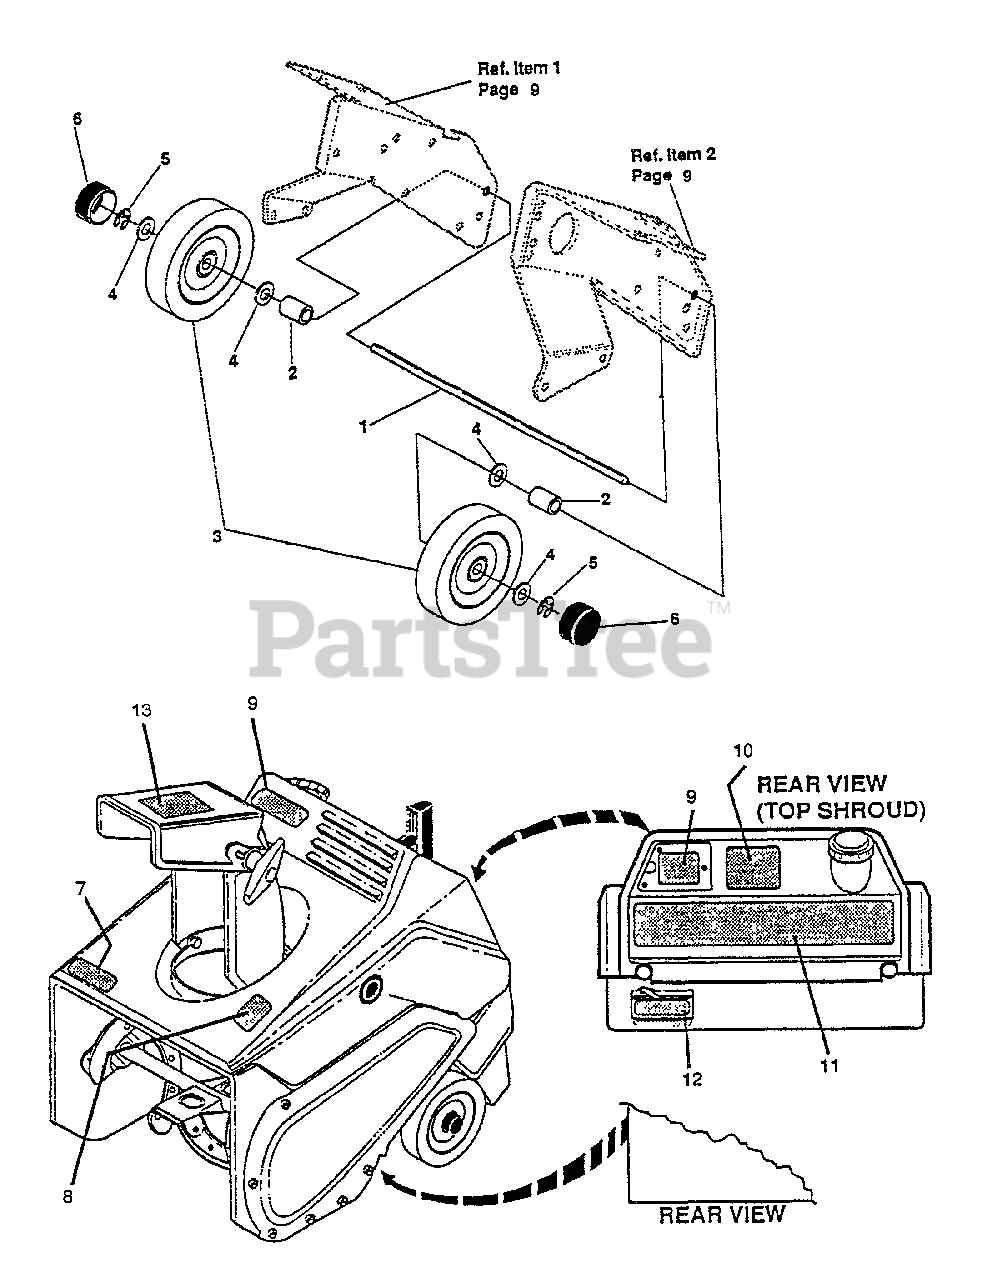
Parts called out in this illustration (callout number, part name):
1	SHAFT, AXLE 5/21
2	SPACER
3	WHEEL ASSY
4	WASHER
5	RING, RETAINING
6	CAP, HUB
7	LABEL - ECHO
8	LABEL - DANGER
9	LABEL - MODEL ST-4500
9	LABEL - MODEL ST-4500E
10	LABEL - STARTING
11	LABEL - CONTROL PANEL
12	LABEL - CHOKE
13	LABEL - DANGER
